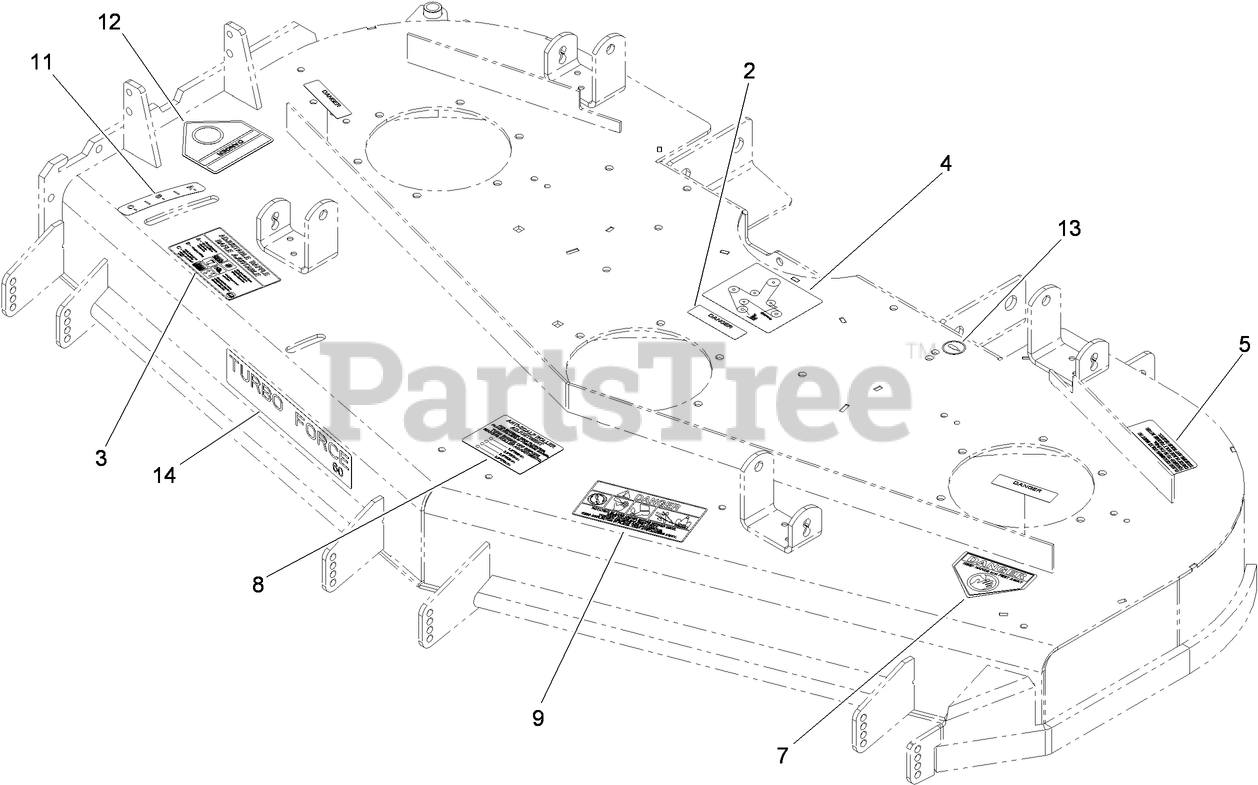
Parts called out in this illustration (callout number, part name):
2	DECAL-COVER, MISSING
3	DECAL-ADJUSTMENT, BAFFLE
4	DECAL-ROUTING, BELT
5	DECAL-TORQUE
7	DECAL-DANGER
8	DECAL-SCALP, ANTI
9	DECAL-DANGER, THROWN OBJECT
11	DECAL-SETTING, BAFFLE
12	DECAL-DANGER
13	DECAL-GREASE
